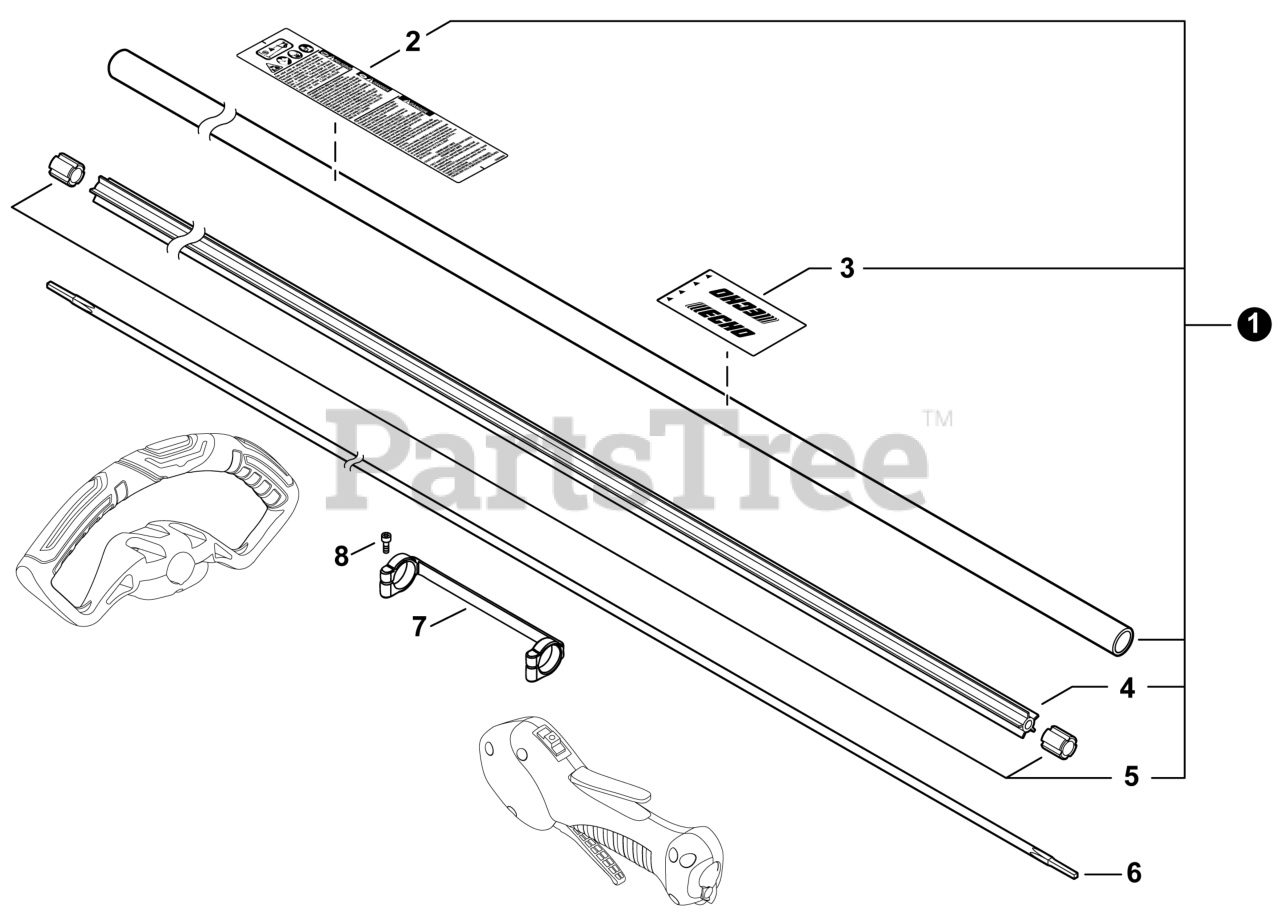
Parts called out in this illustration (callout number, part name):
1	MAIN PIPE ASSY
2	LABEL - CAUTION
3	LABEL - HANDLE LOCATION
4	LINER, FLEXIBLE 21.6x1420
6	DRIVESHAFT - FLEXIBLE
7	COLLAR, MAIN PIPE, 24
8	BOLT, TORX 4x20
